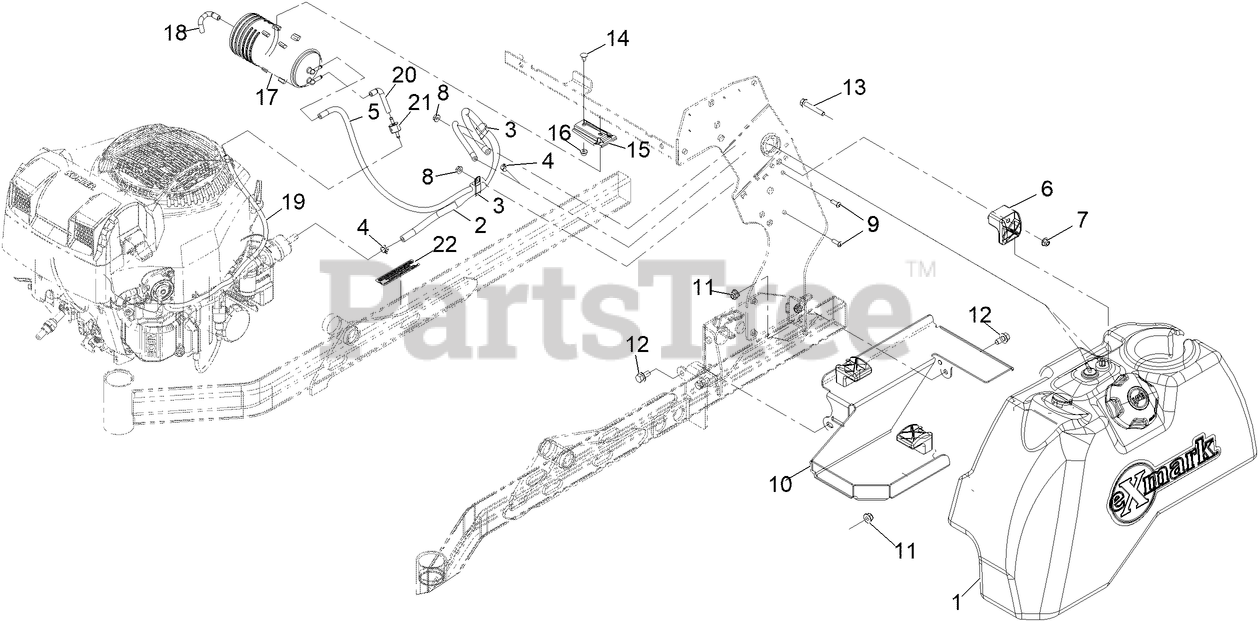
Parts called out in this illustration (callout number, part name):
1	ASM, FUEL TANK 8 GAL
2	HOSE-FUEL
3	CLAMP-R, DOUBLE TUBE
4	CLAMP-HOSE
5	Hose-Fuel
7	NUT-HF, NI
9	SCREW-HSBH
10	Bracket, Fuel Tank
11	NUT-HF, NI
12	Screw-HH Flg 3/8-16 X 3/4
13	SCREW-HHF
14	SCREW-CARR
15	BRACKET-CANISTER, CARBON
17	CANISTER-CARBON, 800CC
18	HOSE-VENT, FORMED
19	Hose, Emissions
20	HOSE-VENT, FORMED
21	VALVE-CHECK, VACUUM
22	DECAL-ARRESTOR, SPARK
